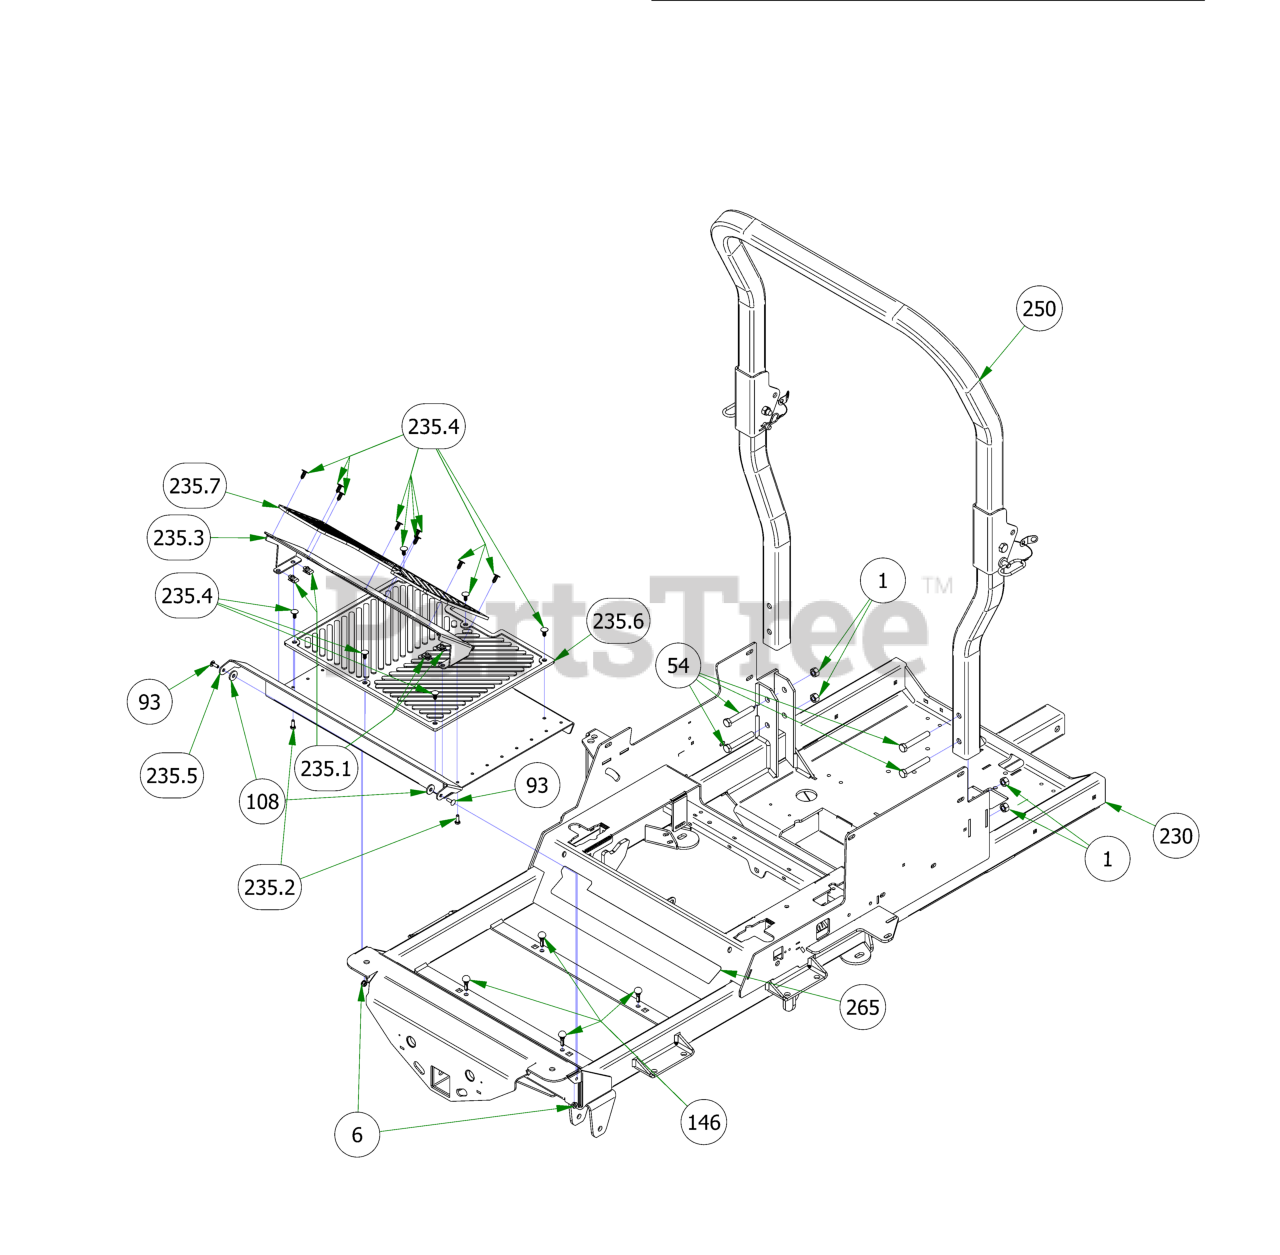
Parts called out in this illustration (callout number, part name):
1	1/2-13 HEX 2-WAY REVERSIBLE CENTER LOCKNUT Grade B ZINC
6	1/4-20 NYL INSERT FLANGE LOCKNUT ZINC
54	1/2-13 X 3-1/4 HEX CAP SCREW (GR.5) ZINC
93	1/4-20 X 3/4 CARRIAGE BOLT ZINC
108	.360 ID X .983 OD X .120 THICK FLAT WASHER NYLON
146	2023 Floor Board Rubber Bumper
230	2019 Renegade Gas Frame - Powdercoated
235	R-Series Floorboard Assembly
235.1	1/4-20 Cage Nut
235.2	1/4-20 X 3/4 HEX CAP SCREW (GR.5) ZINC
235.3	OUTLAW ADJUSTABLE FOOT PLATE-ORANGE
235.4	Ratchet Fastener
235.5	2019 Outlaw Floorboard
235.6	MAT (FLOOR)
235.7	MAT (FOOT PLATE)
250	2019 2X2 Folding ROPS
265	2019 Renegade Cooler Cover Decal
